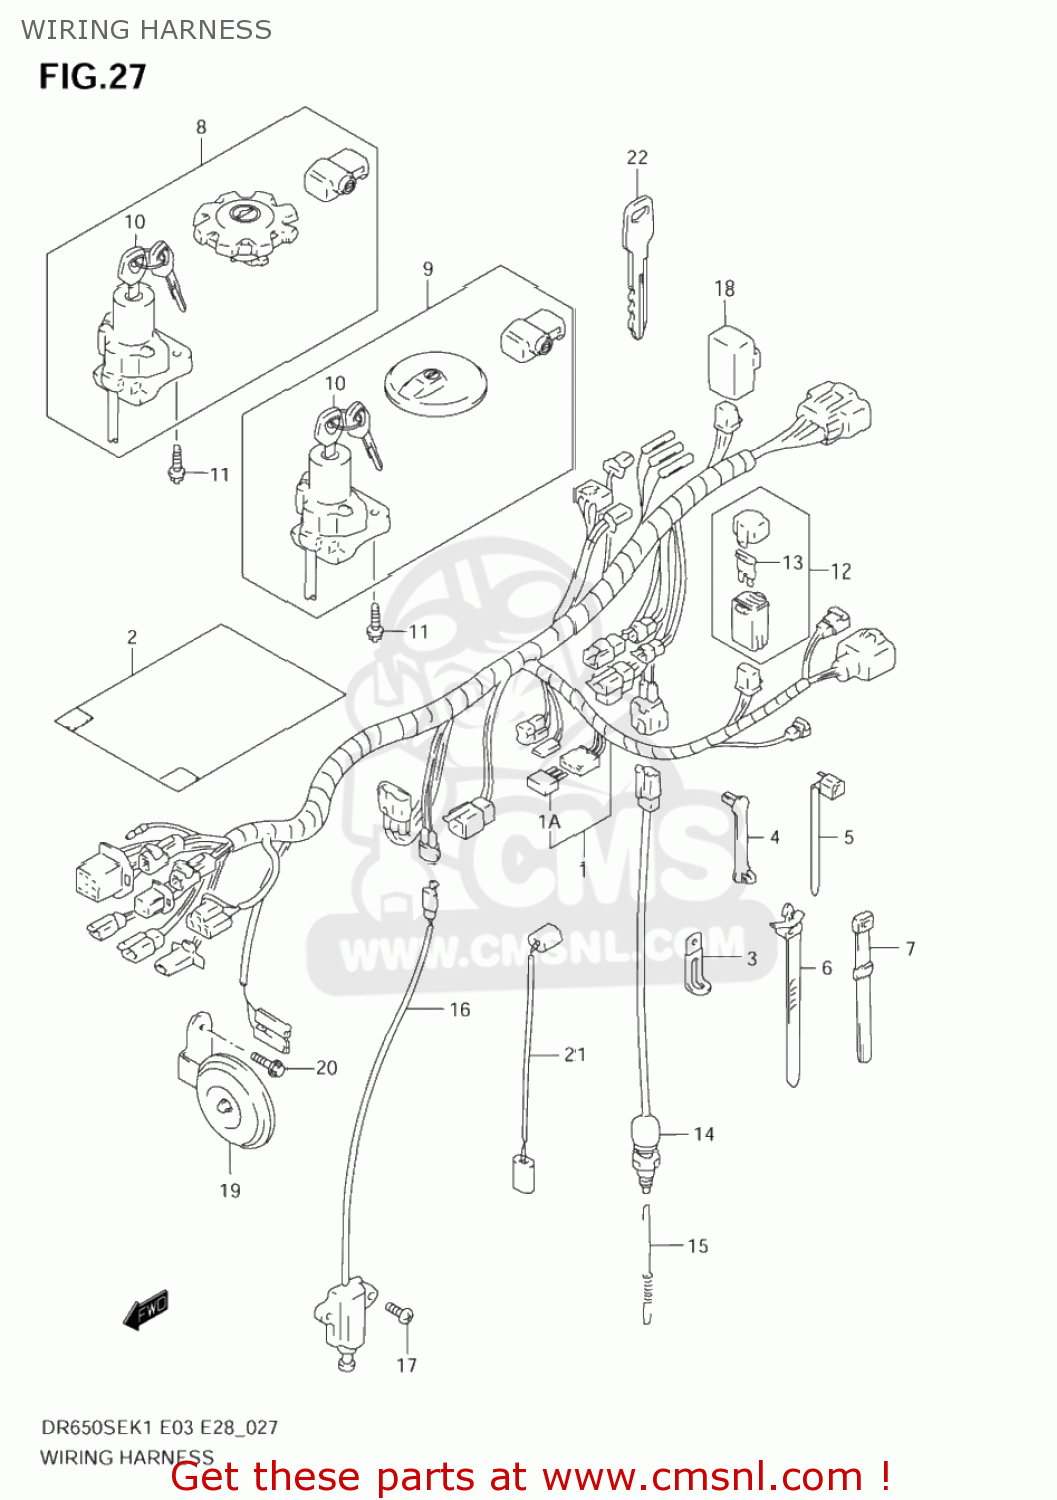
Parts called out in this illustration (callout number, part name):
1	HARNESS,WIRING
1A	DIODE(STANLEY DE8804)
2	COVER,WIRING HARNESS
3	CLAMP(L:45)
4	CLAMP(L:33)
5	CLAMP(L:95)
6	CLAMP(L:90)
7	CLAMP(L:120)
8	LOCK SET
9	LOCK SET
10	LOCK ASSY,STEERING
11	BOLT(8X20)
12	BOX ASSY,FUSE
13	FUSE(10A)
14	SWITCH ASSY,STOP LAMP
15	SPRING
16	SWITCH ASSY,SIDE STAND
17	SCREW 6X16
18	RELAY ASSY
19	HORN ASSY
20	BOLT
21	WIRE,THROTTLE SENSOR
22	KEY,BLANK
